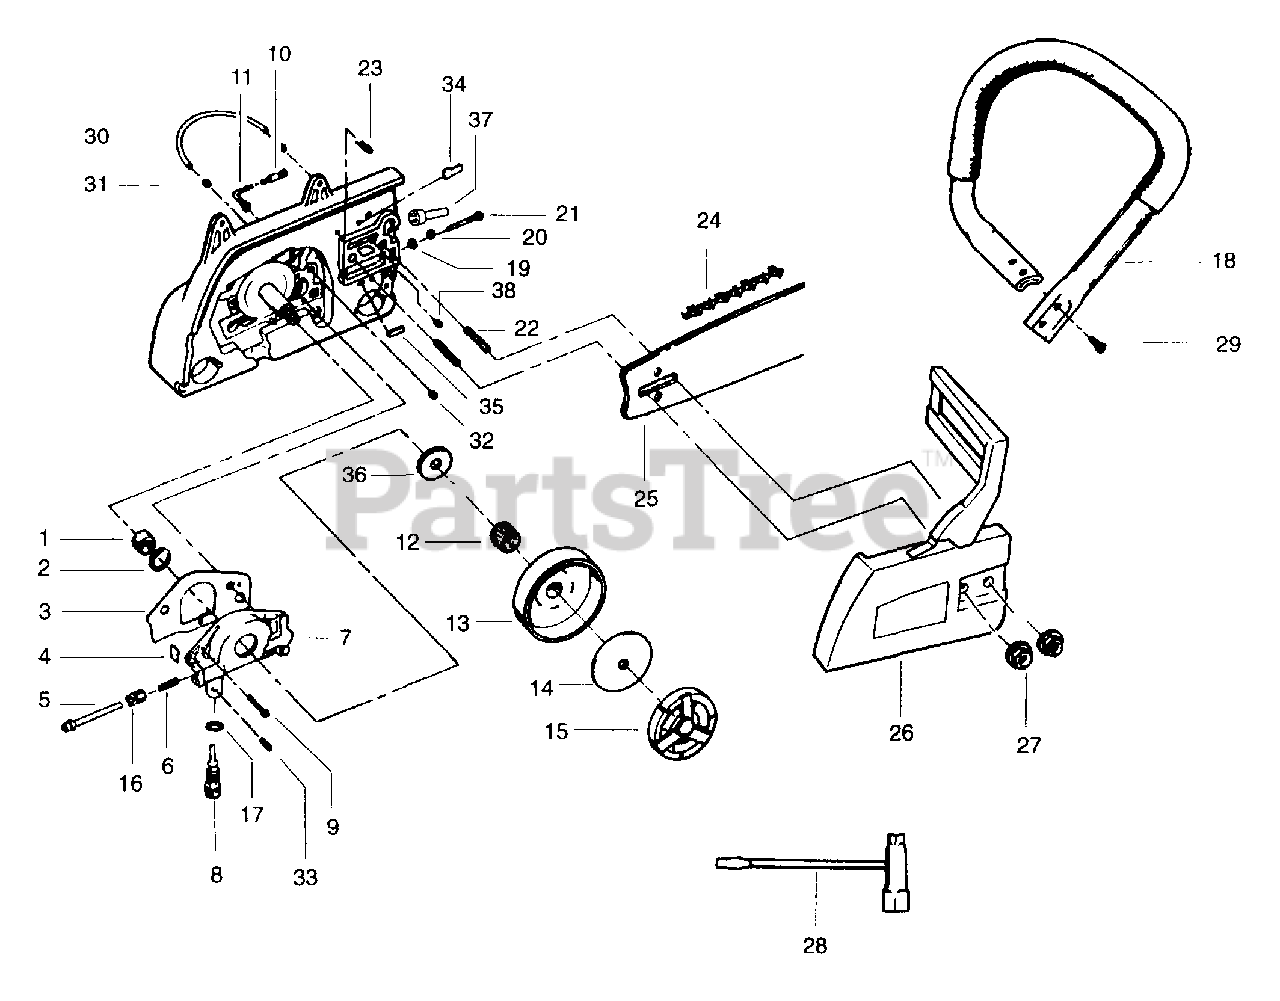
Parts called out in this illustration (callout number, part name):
1	Wire - Worm Gear
2	Seal - Oil Pump
3	Gasket Kit
4	Dust Plug
5	Shaft Assy
6	Spring - Plunger
7	Oil Pump Ass'y. Kit
8	Screw - Oiler Adjusting
9	Screw
10	Oil & Filter Pickup
11	Line - Intake Oil
12	Clutch Bearing
13	Drum & Sprocket Ass'y.
14	Clutch Plate
15	Clutch Ass'y.
16	Gear - Spur
17	"O" Ring
18	Handlebar Ass'y.
19	Bar Adjusting Pin
20	Retainer - Bar Adjust
22	Bar Stud
23	Cotter Pin
24	Chain - 20" (33SL)
25	Bar - 20" (SN)
26	Chain Brake Ass'y
27	Nut - Bar Mounting
28	Scrench
30	Line - Oiler
31	Sleeve - Ferrule
32	Nut - Slotted Tube
33	Pin-Adjustment Screw
34	Chain Pad - Top
35	Chain Pad
36	Washer - Thrust
37	Crankcase Plug
38	Fitting - Bar Pad
